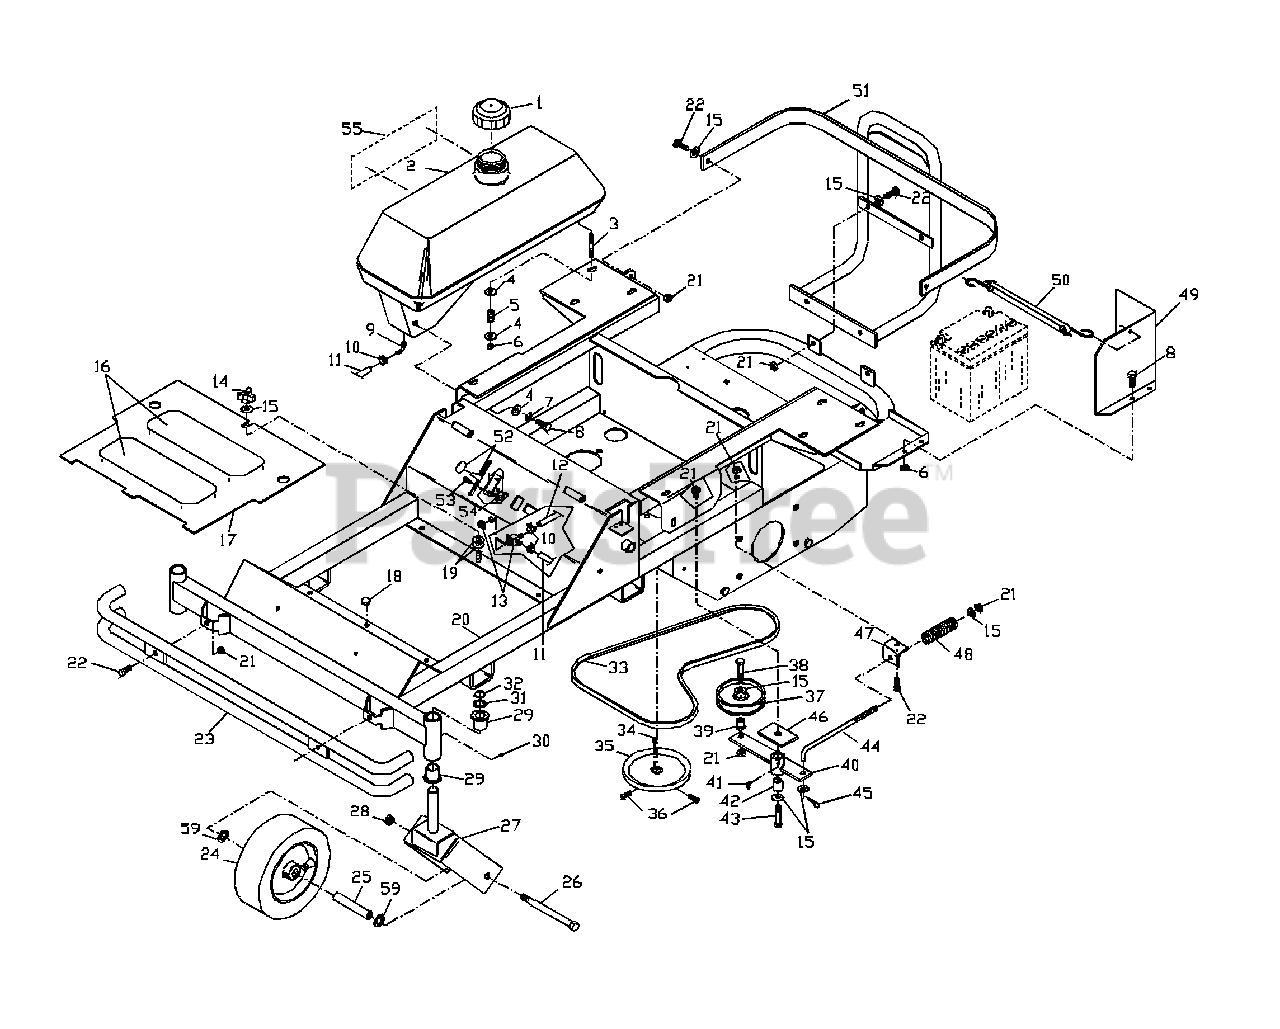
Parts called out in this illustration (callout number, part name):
1	FUEL CAP
2	FUEL TANK RT.
3	5/16C STUD
4	5/16 FLAT WASHER
6	NUT 5/16C CENTERLOCK
7	5/16 LOCKWASHER
8	HCS 5/16C X 3/4
9	90 DEG. HOSE BARB
10	HOSE CLAMP
11	FUEL LINE, TANK
12	FUEL LINE, ENGINE
13	FUEL VALVE
15	3/8 FLAT WASHER
16	ANTI-SKID PAD
17	FOOTPLATE
18	BUMPER, RUBBER
19	3/8 DISC WASHER
20	FRAME W/DECALS (KAW)
20	FRAME W/DECALS (KOHLER)
21	NUT 3/8C CENTERLOCK
22	HCS 3/8C X 1
23	BUMPER, FRONT
24	CASTER TIRE
24	ROLLER BEARING
24	ZERK
24	FLANGED BEARING
26	HCS 1/2C X 5 1/2
27	YOKE WELDMENT
28	NUT 1/2C NYLOC
29	FLANGE BUSHING
31	MACHINERY BUSHING
32	7/8" RETAINING RING
34	KEY 5 MM SQ. X 25 MM
36	5/16C X 5/8 SQ. HEAD
37	IDLER PULLEY
38	HCS 3/8C X 1 3/4
39	IDLER FLANGE BUSHING
40	IDLER ARM WELDMENT
41	45 DEG. ZERK
42	PIVOT BUSHING
43	HCS 3/8C X 3
44	TENSION ROD
45	COTTER PIN
46	SUPPORT PLATE
47	TENSION BRACKET
48	COMPRESSION SPRING
49	BATTERY GUARD W/DECALS
50	BATTERY STRAP
51	ENGINE GUARD W/DECALS
52	THROTTLE CABLE
53	#10-24 X 1/2 HCS
54	#10-24 NYLOC NUT
55	DECAL, ZTH4218
55	DECAL, ZTH4221
55	DECAL, ZTH4818
55	DECAL, ZTH4820
55	DECAL, ZTH4821
56	HCS 3/8C X 2 1/4 GD5
57	WEIGHT BLOCK
58	CHOKE CONTROL (KOHLER)
59	MACHINERY BUSHING
